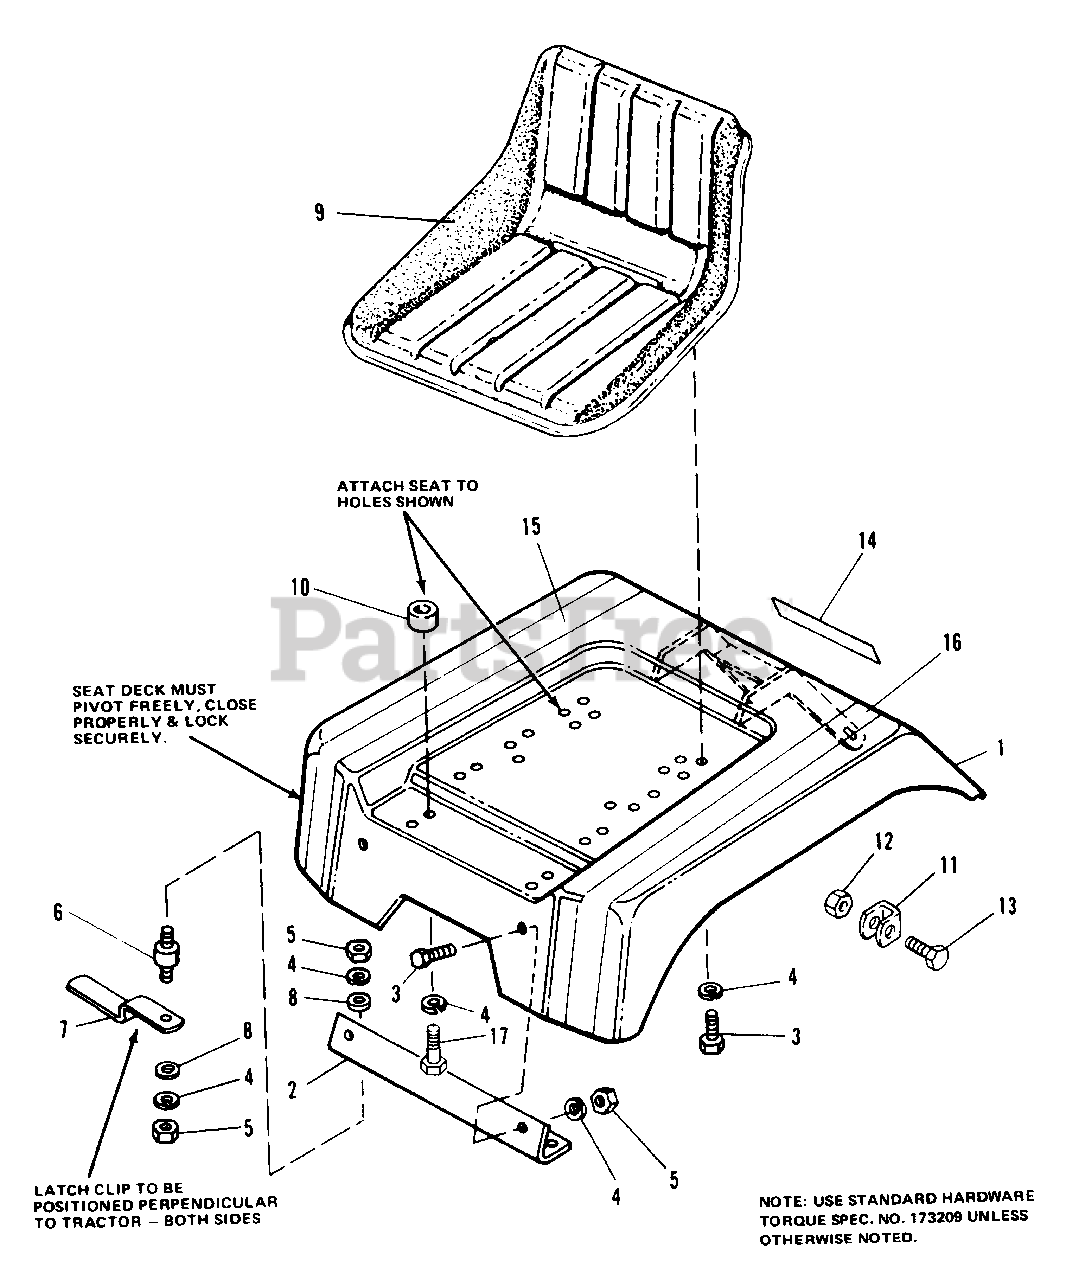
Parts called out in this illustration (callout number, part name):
1	SEAT, Deck
2	BRACKET, Frt. Seat Deck
3	CAPSCREW, 5/16-18 x 5/8
4	LOCKWASHER, 5/16
5	NUT, Hex, Full, 5/16-18
6	CONNECTOR, Cushion
8	WASHER, 1/4
11	STOP, Seat Deck
12	LOCKNUT, Hex, 3/8-16
13	CAPSCREW, Hex, 3/8-16 x 1-1/4
14	DECAL, Simplicity
15	DECAL, Stripe, R.H.
16	DECAL, Stripe, L.H.
17	CAPSCREW, Hex Hd., 5/16-18 x 1 1/4
